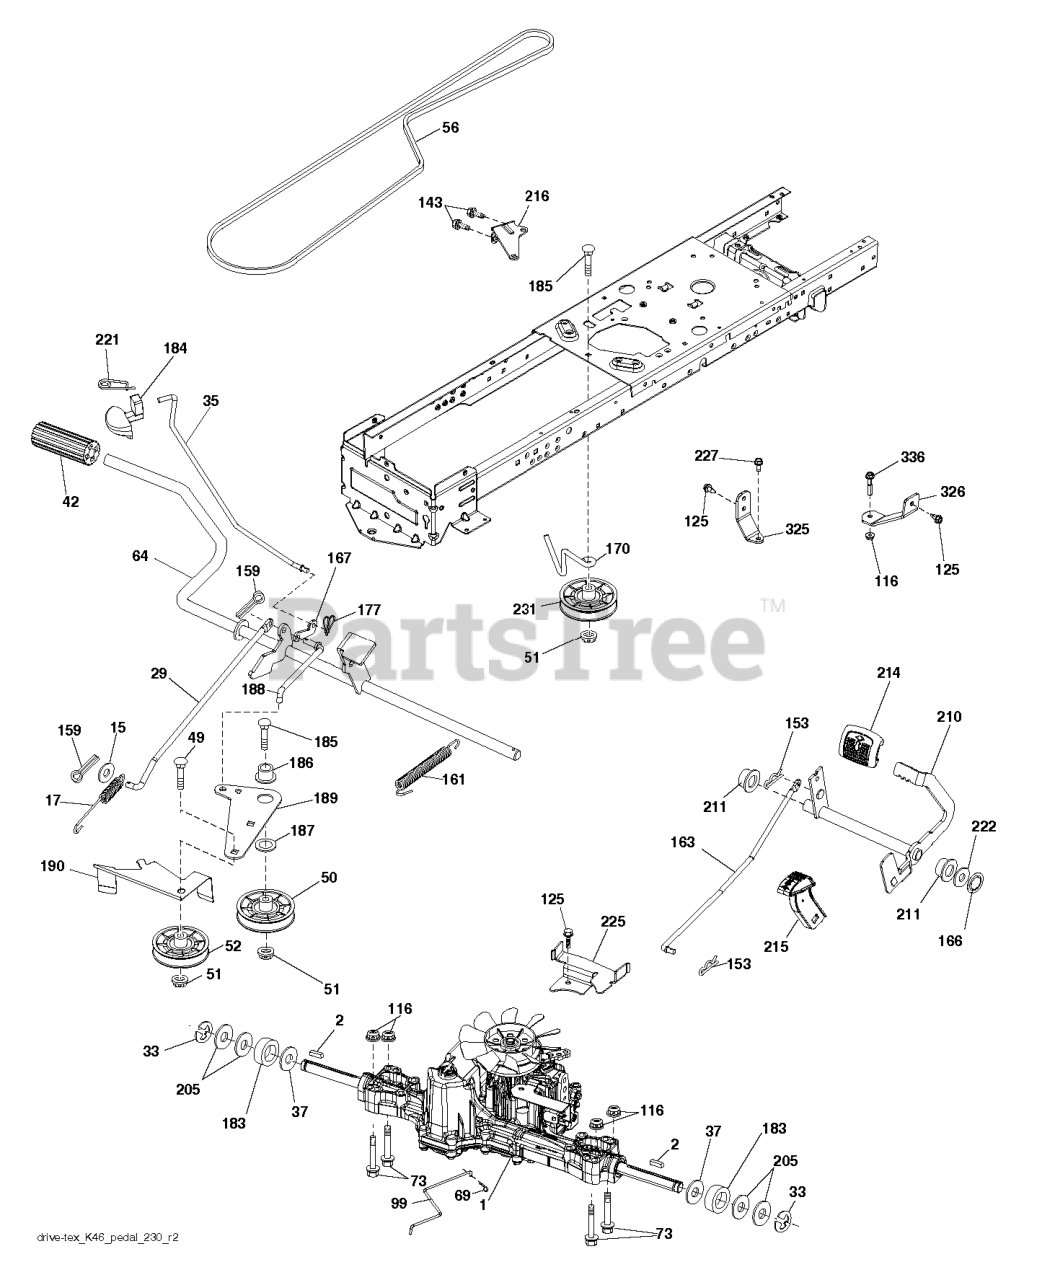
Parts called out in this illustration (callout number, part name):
2	SQUARE KEY
15	WASHER PLAIN WASHER 3/8 X 0.08
17	SPRING.BRAKE.K46.GREEN
29	ROD.BRAKE.K46
37	WASHER.HARDENED
42	PEDAL COVER
50	IDLER.FLAT.910.OFFSET
51	NUT LOCK FLG 3/8-16 UNC
52	IDLER.V-GROOVE.910.OFFSET
64	SHAFT.ASM.PEDAL.BRK.CNTR
69	HAIRPIN.SOFT.ZINC.059X1.125
99	ARM.PIVOTING.TCRD.GEN2.5.BAGGE
125	SCREW
153	RETAINER M
161	SPRING, RETURN LT
166	NUT.PUSH.625
167	LATCH.BRAKE.SPRING
170	KEEPER.CENTER SPAN.1.688
177	PIN COTTER;LOCKING;BOWTIE;1IN
183	SPACER AXLE
184	HANDLE.PARKNG BRK.PRED.LT.428
186	SPACER.RETAINER
188	LINK.CLUTCH.GROUND DRIVE.LONG
189	BELLCRANK.GROUND.DRIVE.TEX.
190	KEEPER.BELLCRANK.DRIVE
210	ROCKER.ASM.PEDAL.CONTR
211	BEARING.NYLON
214	PEDAL.FORWARD.PAD.TEX
215	PEDAL.COVER.REVERSE.CRD.X428BK
216	BRACKET.PULLEY.IDLER.W/TEX
221	RETAINER.SPRING.CLIP.H
222	WASHER 21/32 X 1-1/4 X 10 GA.
225	KEEPER.BELT.TRANSAXLE.K46
231	IDLER.V-GROOVE.1.688.OFFSET
325	TORQUE.STRAP.K46.LT.LH
326	BRCKT.PNT.TRQ.STP.46.18TIRE.RH
